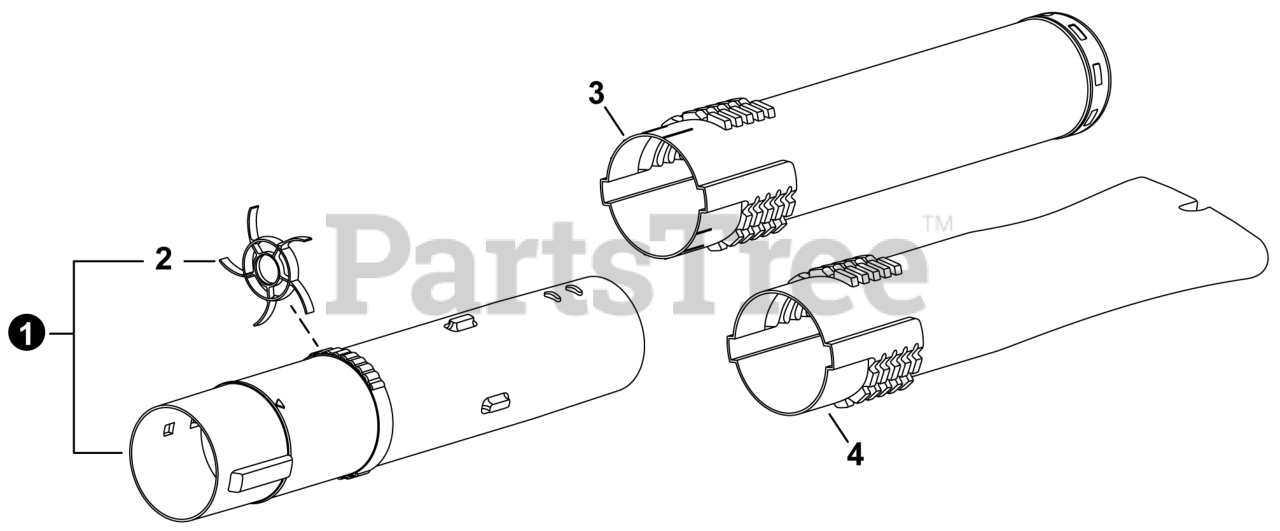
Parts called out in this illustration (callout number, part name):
1	TUBE, BLOWER - STRAIGHT
2	GUARD - BLOWER TUBE
3	TUBE, BLOWER - NOZZLE
4	TUBE, BLOWER - FLARED NOZZLE
